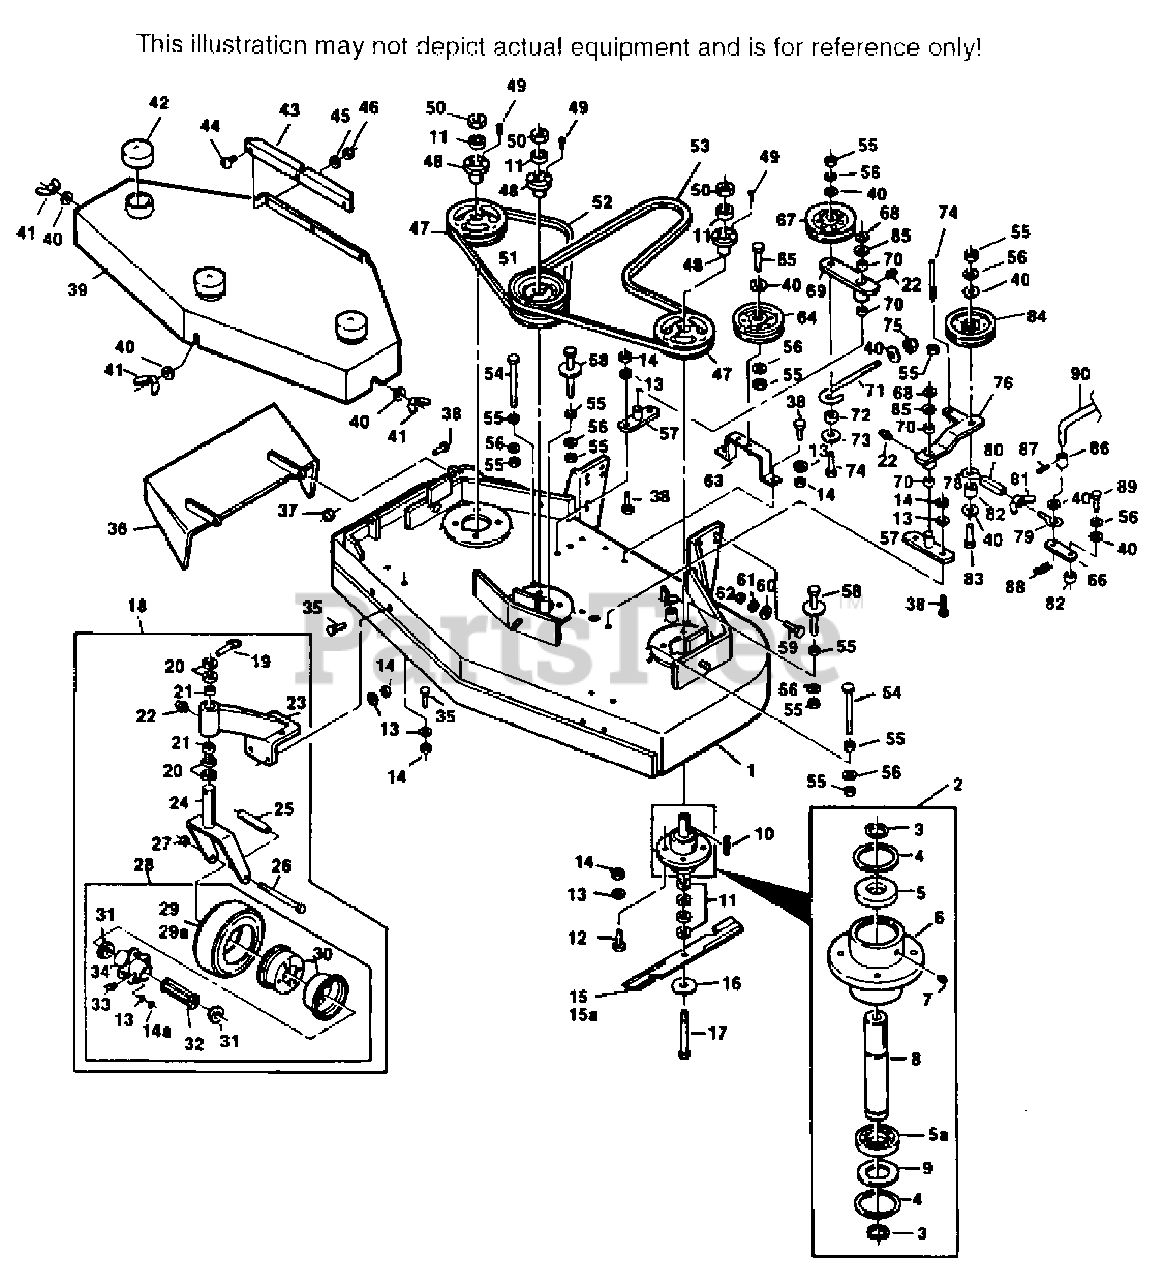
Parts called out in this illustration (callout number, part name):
2	CUTTER SPINDLE ASSY.(INCL. 3-9)
3	RETAINING RING, 1" EXT.-INVERTED
4	RETAINING RING, 2-7/16 INT.-BASIC
5	BEARING, CUTTER SPINDLE LOWER
5A	BEARING, CUTTER SPINDLE UPPER
6	SPINDLE HOUSING
7	GREASE FITTING, STR. 5/16 SERR.
8	SPINDLE, CUTTER BLADE
9	WASHER, 1-15/16 X 2-13/32 X 16 GA.
10	KEY, 1/4 X 1/4 X 2
11	SPACER, CUTTER BLADE
16	FLAT WASHER, 5/8W
17	HEX HEAD BOLT, 5/8-11 X 9-1/2
18	CASTER ASSY, COMP.(INCL. 19-28)
19	QUICK PIN
20	SPACER, CASTER YOKE, 1/2 LONG
21	BRONZE BEARING
22	GREASE FITTING, STR. 1/4-28
23	SUPPORT ASSY.(INCL. 21-22)
24	CASTER YOKE WLD.
25	SLEEVE, CASTER WHEEL BEARING
26	HEX HEAD BOLT, 1/2-13 X 5-1/2
28	WHEEL ASSY.(INCL. 13-14, 14A, 29-34)
29	TIRE ONLY, CASTER WHEEL
29A	INNER TUBE ONLY, CASTER WHEEL
30	RIM PAIR, CASTER WHEEL
31	RETAINER, BEARING, CASTER WHEEL
32	ROLLER BEARING, CASTER WHEEL
33	GREASE FITTING, 45' 1/4-28
34	HUB ASSY. W/BOLTS, CASTER WHEEL
36	DISCHARGE CHUTE WLD.
37	HEX NUT, 5/16-18 ELASTIC STOP
40	WASHER, 25/64 X 15/16 X 12 GA.
41	WING NUT, 3/8-16
43	BELT COVER SKIRT
47	PULLEY(INCL. 48-49)
48	TAPER HUB
51	PULLEY, DOUBLE(INCL. 48-49)
57	IDLER PIVIOT WLD.
58	BELT GUIDE WLD.
60	WASHER, 15/32 X 59/64 X 16 GA.
62	HEX NUT, 7/16-14, ELASTIC STOP
63	IDLER PULLEY SUPPORT
66	CAM LINK
67	IDLER PULLEY, "V" GROOVE
68	RETAINING RING, 3/4 EXT.-"E"69
69	IDLER ARM ASSY.(INCL. 22 & 70)
70	BRONZE BEARING
71	ROD, IDLER PULL, J
72	SPACER, J PULL ROD
73	WASHER, 3/8 X 1-1/2 X 16 GA.
75	HEX NUT, 3/8-16 ELASTIC STOP
76	IDLER ARM ASSY.(INCL. 22 & 70)
77	SPACER, IDLER
78	EYEBOLT, LH
79	EYEBOLT, RH
80	TURNBUCKLE
81	WING NUT, 5/16-18
82	SLEEVE, CAM CLUTCH
84	IDLER PULLEY, BELT CLUTCH
85	WASHER 3/4(49/64 X 1-1/4 X 16 GA.)
86	SLEEVE, CLUTCH ROD
88	HAIR PIN, LARGE
90	BLADE CLUTCH ROD
